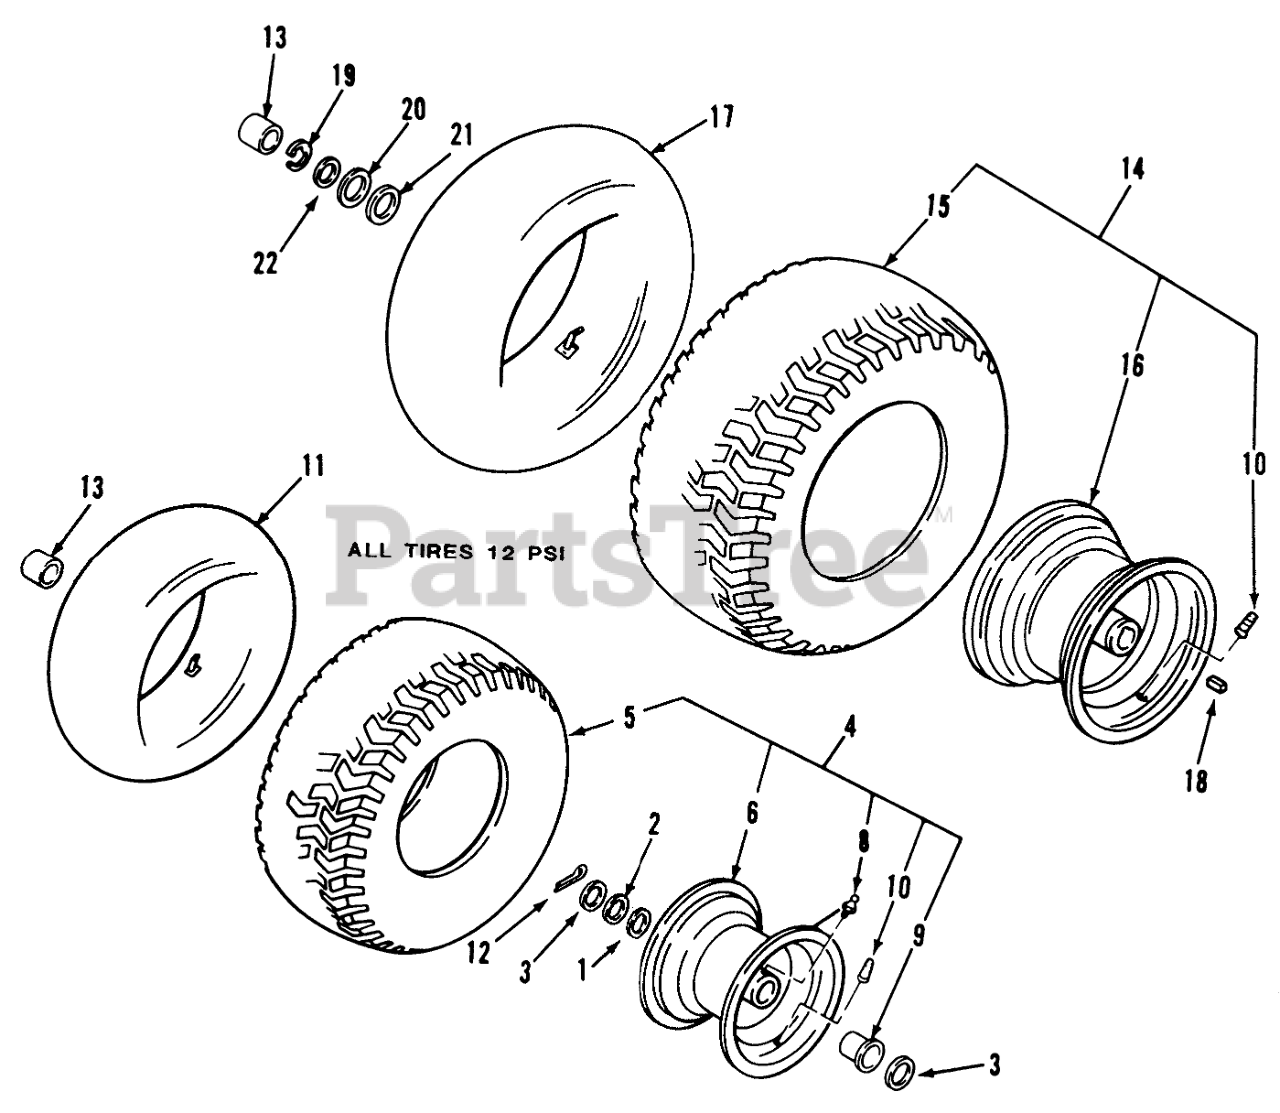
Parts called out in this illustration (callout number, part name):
1	WASHER-SHIM
2	WASHER
3	WASHER-FLAT
4	Front Tire & Wheel (Incl. Ref. #5, 6, & 8-10)
5	TIRE15 X 6.00-6
6	Assembly-Front Wheel (Incl. Ref. #8-10)
8	ZERK-GREASE
9	BUSHING
10	VALVE
12	COTTER PIN-4
13	HUB CAP-FLAT BLACK
13	HUB CAP
14	Rear Wheel & Tire-212-5
14	Rear Wheel & Tire-212-H
15	TIRE 18 X 9.50-8
16	ASSY WHEEL
16	ASSY-WHEEL
17	Tube-Inner
18	SQ KEY
18	Key
19	E Ring
19	Snap Ring
20	WASHER-SHIM
20	Washer
21	WASHER
22	WASHER-FLAT
22	Washer
